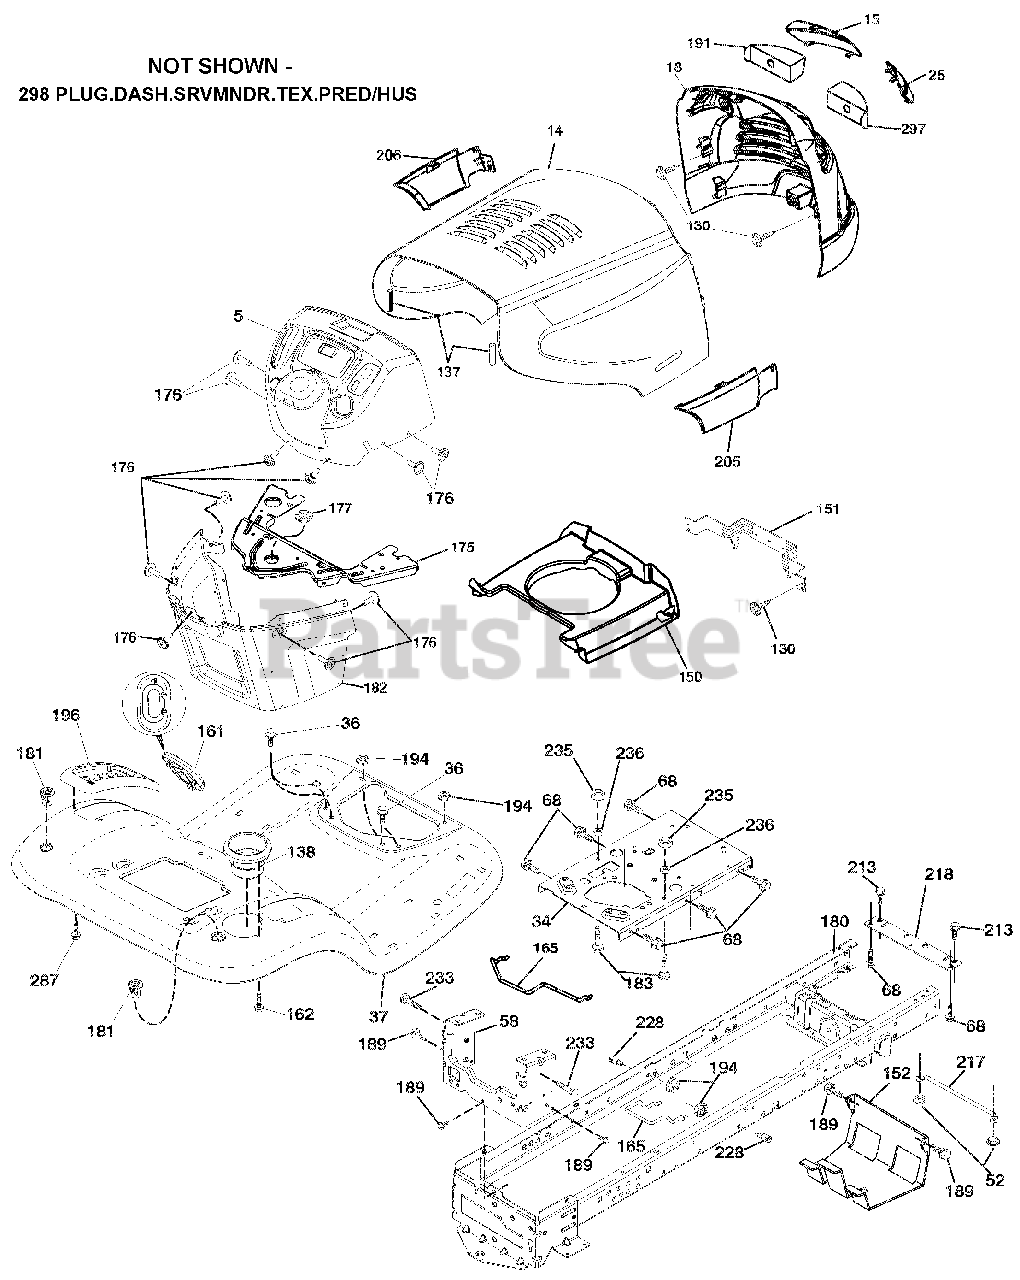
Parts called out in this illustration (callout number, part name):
5	DASH.UPPER.TEX.ELITE.EL.CK.428
14	HOOD.PNT.ELITE.SPL-TP.W-SKIRTS
15	LENS.ELITE-HUSQ.CLEAR.LH
18	GRILLE.ELITE.ARIENS.BLACK
25	LENS.ELITE-HUSQ.CLEAR.RH
34	PLATE.ENGINE.WELDED.CHASSIS
36	SCREW.5/16-18X3/4.SMGML.TAP/R
37	FENDER.TLT.W/CPH.W/FW.422
52	Nut, Hex, Crownlock 5/16-18
58	DRAWBAR.UPPER.2PC.SML.FENDER
68	SCREW.THDROL.5/16-18 X 1/2TYTT
137	BUMPER.HOOD.LARGE. 1.75"
138	CUPHOLDER.TL.TEX.428
150	AIR DUCT.ENGINE.ELITE-SV
151	BRACKET.PIVOT.LASR/ELTE/HUSQLT
152	SHIELD.BROWNING.W/TEX
161	WINDOW.FUEL.LT.TEX.428
162	SCREW.HEX.WSH.HI-LO.1/4X1/2UNC
165	SUPPORT.TANK.REAR.W/TEX
175	CROSSMEMBER.LT
176	SCREW.#10-24X5/8.RND.QUDRX.GIM
177	BUSHING.STEERING.YT/GT
180	CHASS.WLDMT.TL.12GA/2PC.18/22"
181	BUSHING.MNT.FEND.CRGO.BLK.TEX
182	DASH LOWER.LT.CCS
183	BOLT.FIN.HEX.5/16-18UNC X1-1/4
189	SCREW.5/16-18X3/4.SMGML.TAP/BL
191	INSERT.LENS.RFLCT.ELT-HUSQ.
194	Nut, Lock Hex Flange 5/16-18 u
196	CONSOLE ASM.DECKLFT.BL/RBT.TLT
205	SKIRT.SIDE.RH.ELITE HUSQ.428
206	SKIRT.SIDE.LH.ELITE HUSQ.428
213	Bolt, Hex Head 5/16-18 x 3/4
217	ROD.PIVOT.HOOD
218	X-PIECE.HOOD.STOP.NON/STEALTH
228	STUD.FASTNER.W/'D'ANTI-ROTATIO
233	BOLT.SHOULDER
235	SPACER.FENDER
236	NUT.CENTER LOCK.5/16-18 UNC
287	SCREW.HEX.WASHEAD.1/4-20 X 3/8
297	INSERT.REFLECTIVE.RH.
298	PLUG.DASH.SRVMNDR.TEX.PRED/HUS
